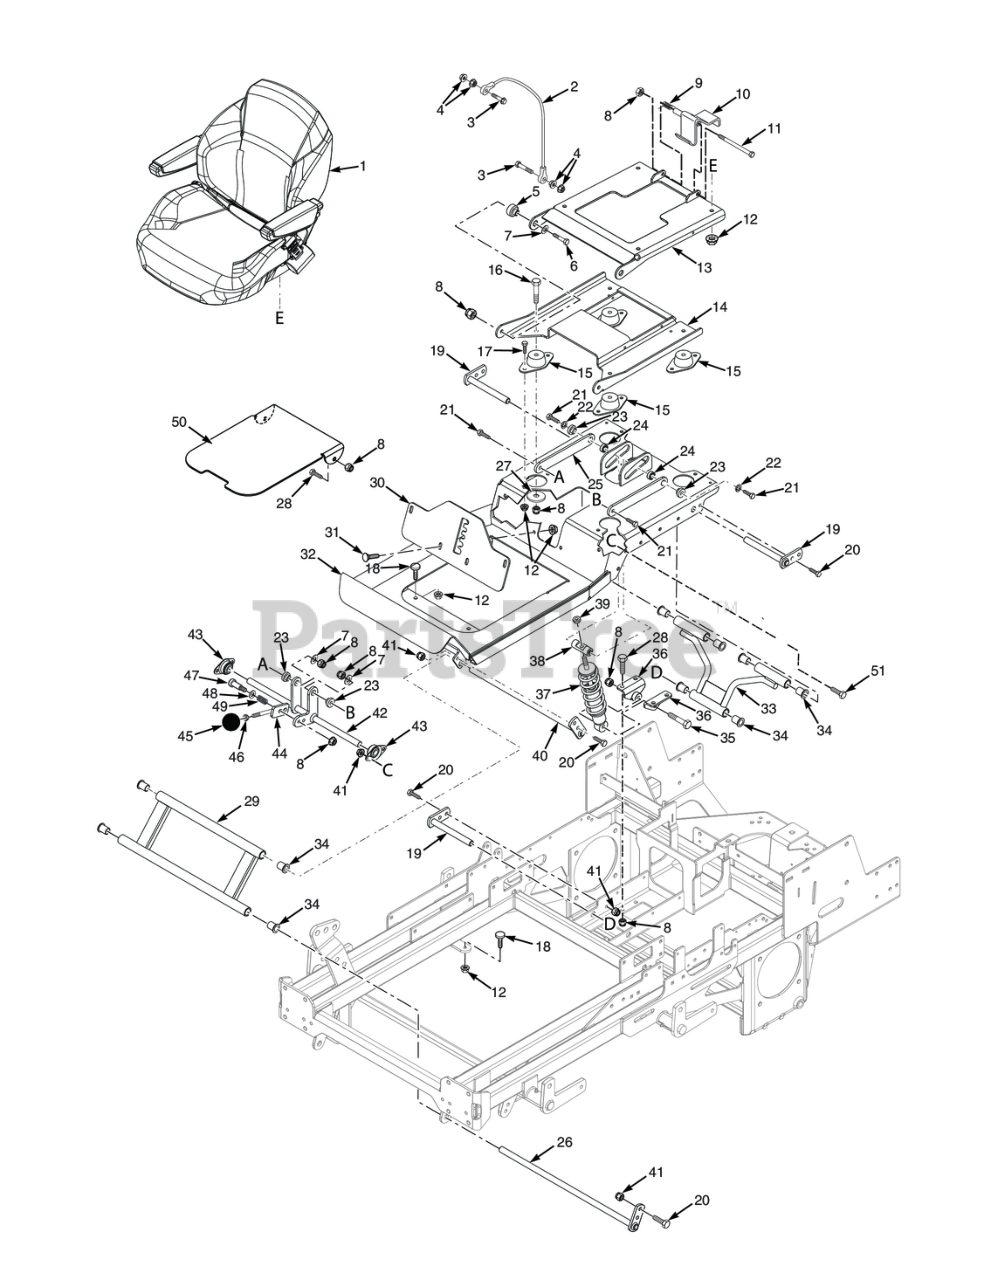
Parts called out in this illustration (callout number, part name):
1	Seat Assembly (INCL 14)
2	Cable, Seat Stop
3	SERR. FLG. HEX HEAD CAPSCREW, 5/16-18 X 3/4
4	NUT, 1/4-20 SERRATED FLANGE HEX HEAD
5	Sleeve, Seat Base Mounting
6	Capscrew, Hex Head 3/8-16 x 2.0"
7	Flatwasher, 3/8" Special (.391 x .938 x .105)
8	HEX NUT, ELASTIC STOP LOCK, 3/8-16
9	Spring, Seat Latch
10	Latch Weldment, Seat
11	Bolt, 3/8-16 x 6.00" Hex Head
12	Nut, Serrated Flange 5/16-18 (Right Front Engine Mounting, Briggs and Kohler Only)
13	Seat Plate Weldment
14	Seat Mounting Plate Weldment w/Decal
15	Isolator, Seat
16	Bolt, Hex Head 3/8-16 x 2-1/4" - 61"
17	BOLT, SERRATED FLANGE HEX HEAD 5/16-18 X 3/4"
18	Bumper, Rubber
19	Shaft Weldment, Rear Op. Platform Pivot
20	Bolt, Heax Head 5/16-18 x 1" (48V / 52V)
21	Bolt, Hex Head, 3/8-16 x 1-1/2"
22	Lockwasher, 3/8" Spring, Kawasaki FX / FS
23	BUSHING, SPEED ADJUSTMENT LEVER
24	Bearing
25	Link, Suspension Seat Tensioner
26	Pin Weldment, Op Platform Lower Pivot
27	Flatwasher, 3/8-.406 x 2.25" x .1875
28	Bolt, Hex Head, 3/8-16 x 1 Gr. 5
29	Suspension Pivot Assembly, Front
30	Bracket, Suspension Adjustment w/Decal
31	Bolt, Carriage 5/16-18x1" (large frame units only)
32	Seat Mounting Base Weldment w/Decal
33	Suspension Pivot Assembly, Rear
34	Bearing, .625 ID Plastic
35	Capscrew, Hex Head 3/8-16 x 2.75"
36	Mount Weldment, Shock
37	Shock Absorber, Suspension
38	Mount, Suspension Shock
39	Nut, Elastic Stop 3/8-16, grade 8 black
40	Pin Weldment, Op Platform Upper Pivot
41	HEX NUT, ELASTIC STOP LOCK, 5/16-18
42	Pivot Weldment, Suspension Tensioner
43	Bearing, Self Aligning - 5/8 I.D.
44	Adjustment Lever, Suspension
45	Knob, OCDC Lever
46	HEX NUT, JAM 3/8-16
47	Bolt, Shoulder 3/8 x 1"
48	Flatwasher, 3/8 (.406 x .812 x .065)
49	Spring, Speed Control Slide
50	Cover, Foot Plate
51	BOLT, SERRATED FLANGE HEX HEAD 5/16-18 X 3/4"
